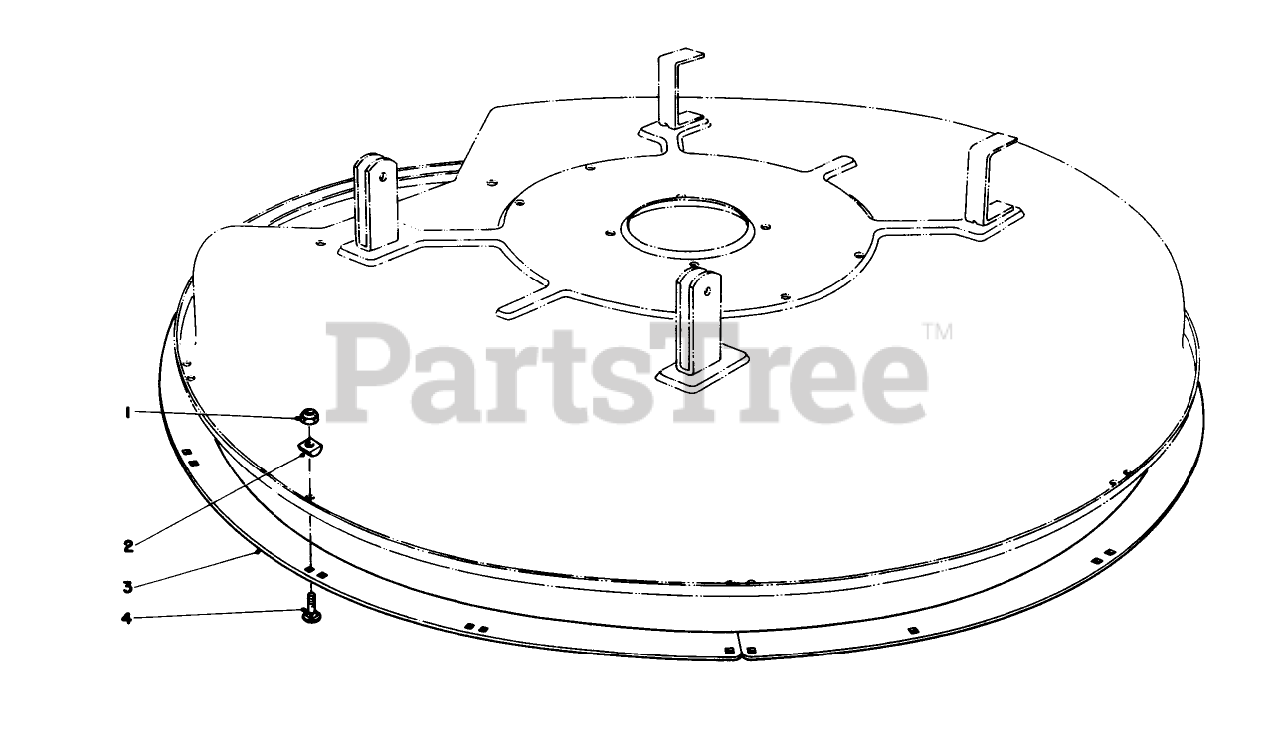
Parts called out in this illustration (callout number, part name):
1	NUT-LOCK, NI
3	DECK RING *B
4	BOLT-CARR
